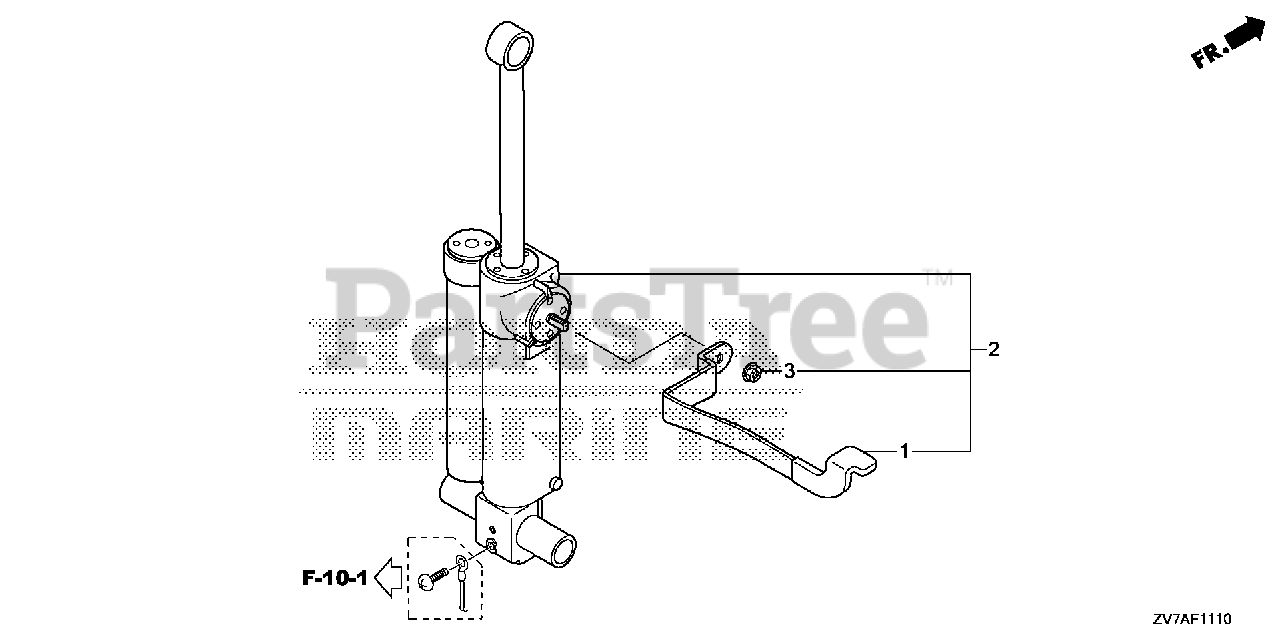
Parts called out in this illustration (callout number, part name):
1	LEVER, TILT
2	SHOCK ABSORBER ASSY., GAS
3	NUT, SELF-LOCK (6MM)
